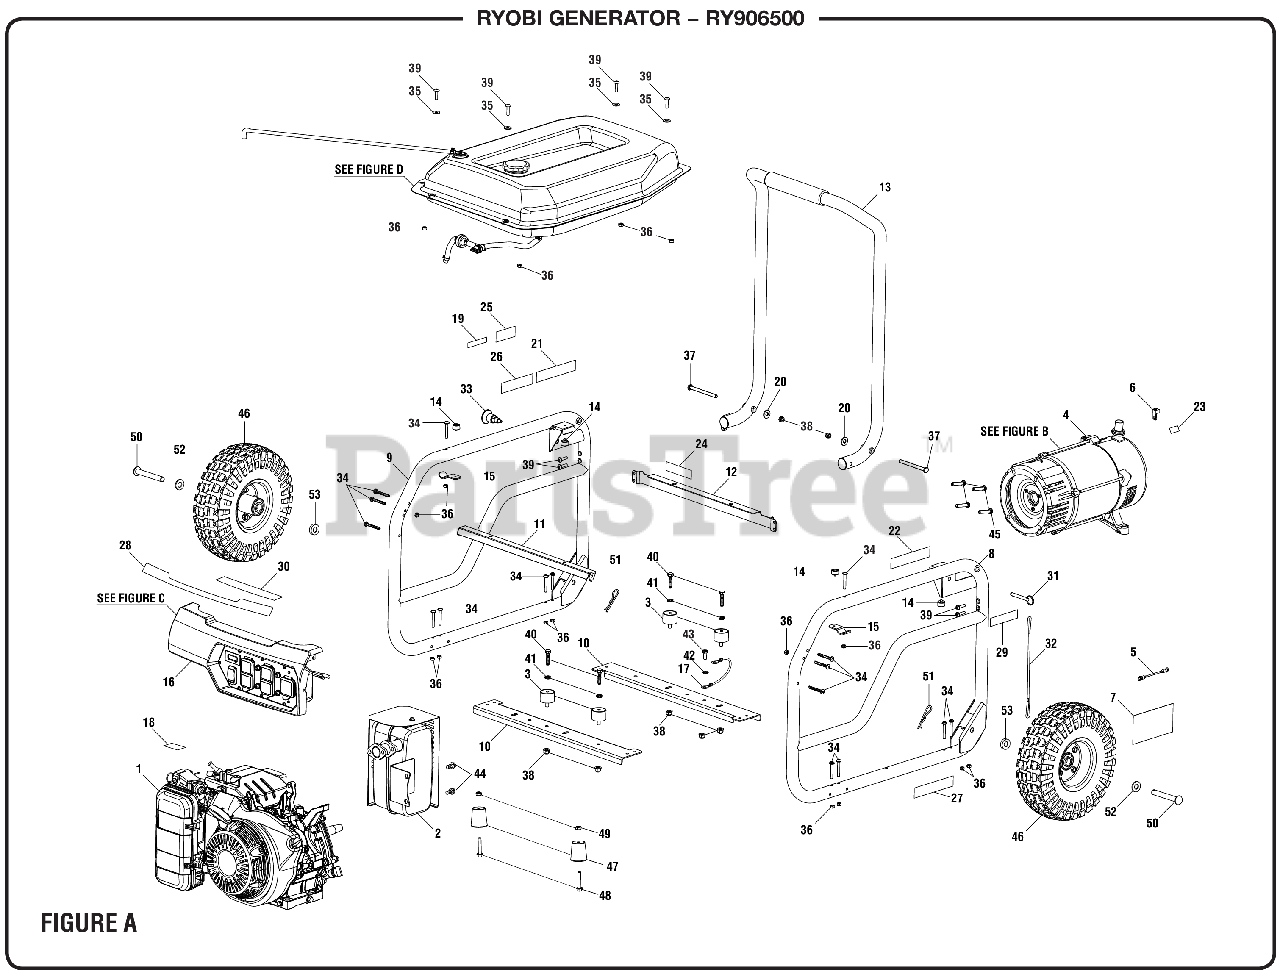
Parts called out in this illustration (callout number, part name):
1	Engine (Honda)
2	Muffler Assembly
3	Isolator Generation 7
4	Generator Head Assembly (See Figure B)
5	Bonding Wire
6	Ground Lug (1/4-20)
7	Rubber Sheet
8	Frame Assembly (Right)
9	Frame Assembly (Left)
10	Cross Bar
11	Fuel Tank Support (Front)
12	Fuel Tank Support (Rear)
13	Handle Assembly
14	Rubber Bumper
15	Handle Rest Tab
16	Control Panel Assembly (See Figure C)
17	Assembly, ground wire
18	Choke Label
19	Inquires Label (Ryobi)
20	Washer (1/4 in.)
21	Fire Distance Label (Eng/Sp)
22	Risk of Fire Danger Label
23	Ground Label Icon
24	Ground Warning Label
25	Quick Release Pin Label
26	Hot Surface Label (Trilingual)
27	Engine Lubricant Label
28	Performance Label
29	Lock Pin Label
30	Quick Start Label
31	Release Pin (5/16 x 2 in.)
32	Lanyard (3/16 in.)
33	Handle Lock Assembly
34	Screw (M6 x 50 mm, T30 Torx Pan Hd. )
35	Washer (OD17 x ID6.4 x 1.6t)
36	Lock Nut (M6 x 1 mm)
37	Handle Pivot Bolt (M8 x 98 mm, Flat Hd.)
38	Flange Lock Nut (M8 x 1.25 mm)
39	Bolt (M6 x 25 mm,T30 Torx Pan Hd.)
40	Bolt (M8 x 1.25 in., Hex Hd.)
41	Lock Washer (OD14.8 x ID8.5 x 1t)
42	Star Washer (M8)
43	Bolt (M8 x 15 mm, Hex Hd.)
44	Bolt (5/16-24 x 0.6 in., Hex Hd.)
45	Bolt, Wiz (3/8-18 x 1-1/4 in.)
46	Wheel (10 in. x 3 in.)
47	Foot Assembly
48	Bolt (M8 x 1.25 in., Flange Hex Hd.)
49	Lock Nut (M8 x 1.25)
50	Axle Bolt (M10 x 125 mm, Hex Hd.)
51	Hitch Pin (M3)
52	Washer (OD19.75 x ID10.5 x 1t)
